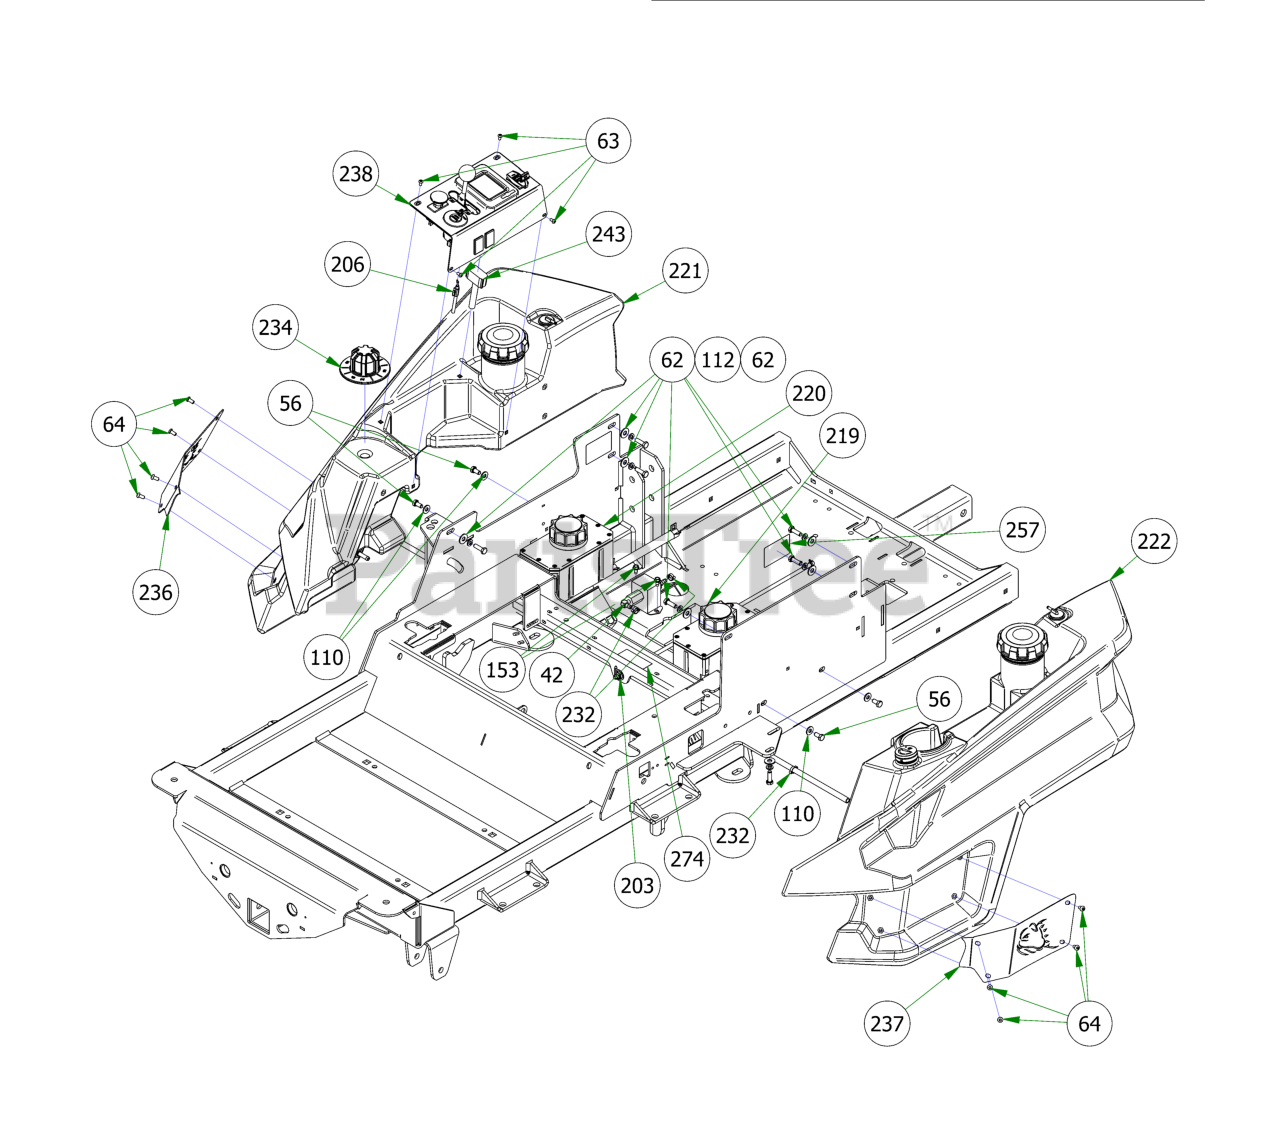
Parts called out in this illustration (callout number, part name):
5	.625 ID x 1.250 OD x .062 THK F/W Nylon
56	5/16-18 x 5/8 Hex Bolt
62	5/16-18 X 1 HEX CAP SCREW (GR.5) ZINC
63	10-32 X 3/8 BUTTON SOCKET CAP SCREW 18-8 STAINLESS STEEL
64	1/4-20 X 1/2 BUTTON SOCKET CAP SCREW 18-8 STAINLESS STEEL
110	1/4 USS FLAT WASHER (3/4 OD) ZINC
111	5/16 USS FLAT WASHER (7/8 OD) ZINC
112	5/16 SPLIT LOCKWASHER ZINC
122	5/8" Split Collar
153	1/4-20 X 1/2 HEX WASHER SLOT (F) TCS ZINC
203	2023 Rebel Rogue Renegade Fuel Line for Kohler
203.5	3 Way Fuel Shut-Off Valve 5/16 x 5/16 x 1/4
206	Outlaw Throttle Cable
219	LH Rogue Hydro Tank Assy
220	RH Rogue Hydro Tank Assy
221	2019 Right Rebel, Rogue, Renagade Fuel Tank (GAS)
222	2019 Left Rebel, Rogue, Renegade Fuel Tank (GAS)
230	2019 Renegade Gas Frame - Powdercoated
232	2 EAR CLAMP 12.5mm-15mm
234	2019 Deck Height Dial
236	2019 Outlaw Fuel Tank Insert - Right
237	2019 Outlaw Fuel Tank Insert - Left
238	Renegade Control Panel Assembly
243	2019 LCD Panel Harness-Renegade
257	Hydraulic Decal
274	R-Series Shut Off Valve Decal
